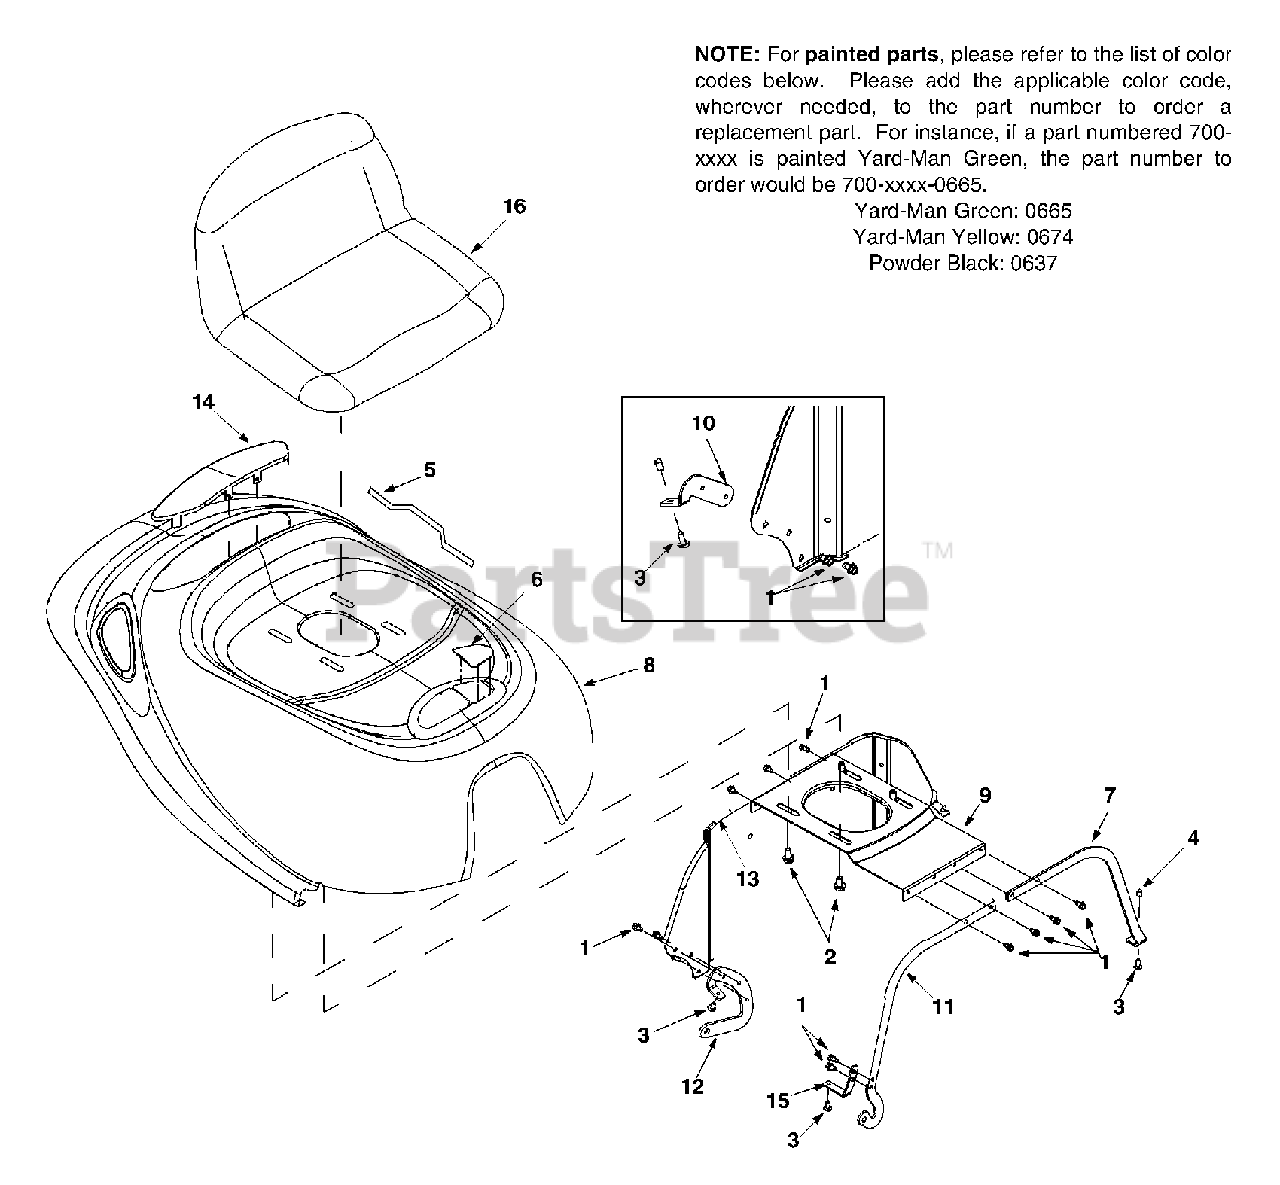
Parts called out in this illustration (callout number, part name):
1	TT Screw 1/4-20 x 0.5
2	TT Screw 3/8-16 x 0.62
3	Torx AB Screw 1/4-14 x 0.625
4	Rod End Grip
5	Trim Strip
6	Grass Bag Lens
